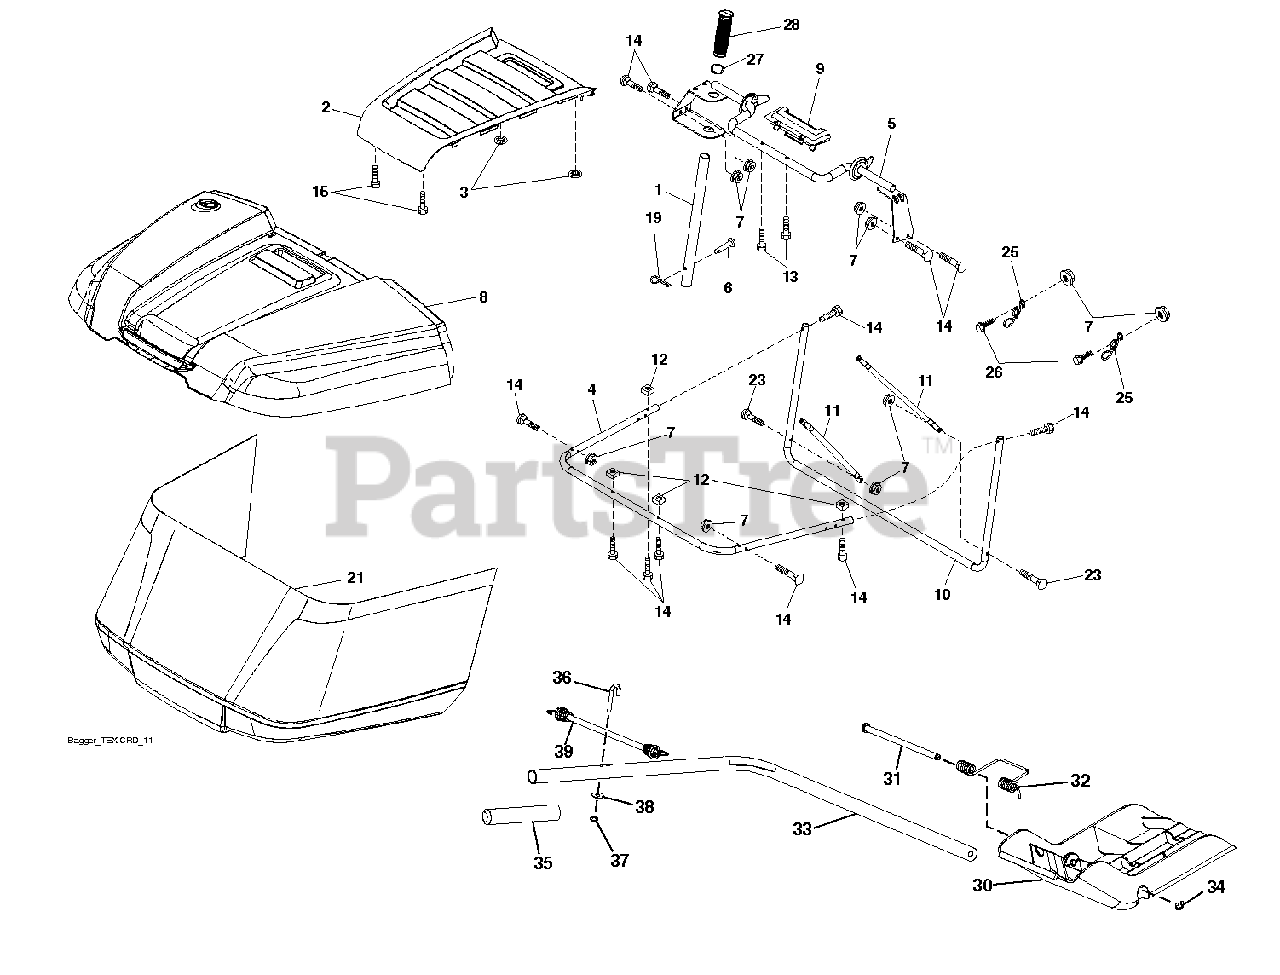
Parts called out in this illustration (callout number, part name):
1	TUBE.HANDLE.BAGGER.CRD/SRD.BLA
2	APPLIQUE.TOP.BAG.SRD.ORANGE
3	NUT.PUSH.156
4	SUBASM.TOP.TUBE.TEX.CRD
5	FRAME.ASM.TOP.BAGGER.SRD
6	RIVET,DRILLED
7	NUT T
8	BAGGER.TOP.SRD.APPLIQUE
9	INSERT.HANDLE.BAGGER.(2 2)
10	FRAME FRAME.FRONT.TEX.CRD
11	BRACE BRACE SIDE TUBE
12	NUT.SQUARE.1/4
13	SCREW.1/4X1.150.HXWSH
14	BOLT.SHOULDER.HX.WSH.1/4X1.150
15	SCREW,#8.FLAT.HEAD.DRILL.TIP
19	PIN.COTTER.5/16.BOW TI
21	BAG SUBASM. TEX CRD GEN 2 HUSQ
25	SPRING.LATCH.BAGGER.SRD
26	SCREW HEX CRT
27	RB GROMMET.RUBBER.SRD
28	GRIP.HANDLE.BLACK
30	PLUG PLUG
31	PIN PIN.HINGE
32	SPRING SPRING DOUBLE TORSION
33	SHAFT SHAFT TEX CRD MULCH PLU
34	E-RING.5/16"
35	GRIP GRIP MULCH PLUG HAND
36	BOLT BOLT J
39	BUBGEE BUBGEE TEX CRD
